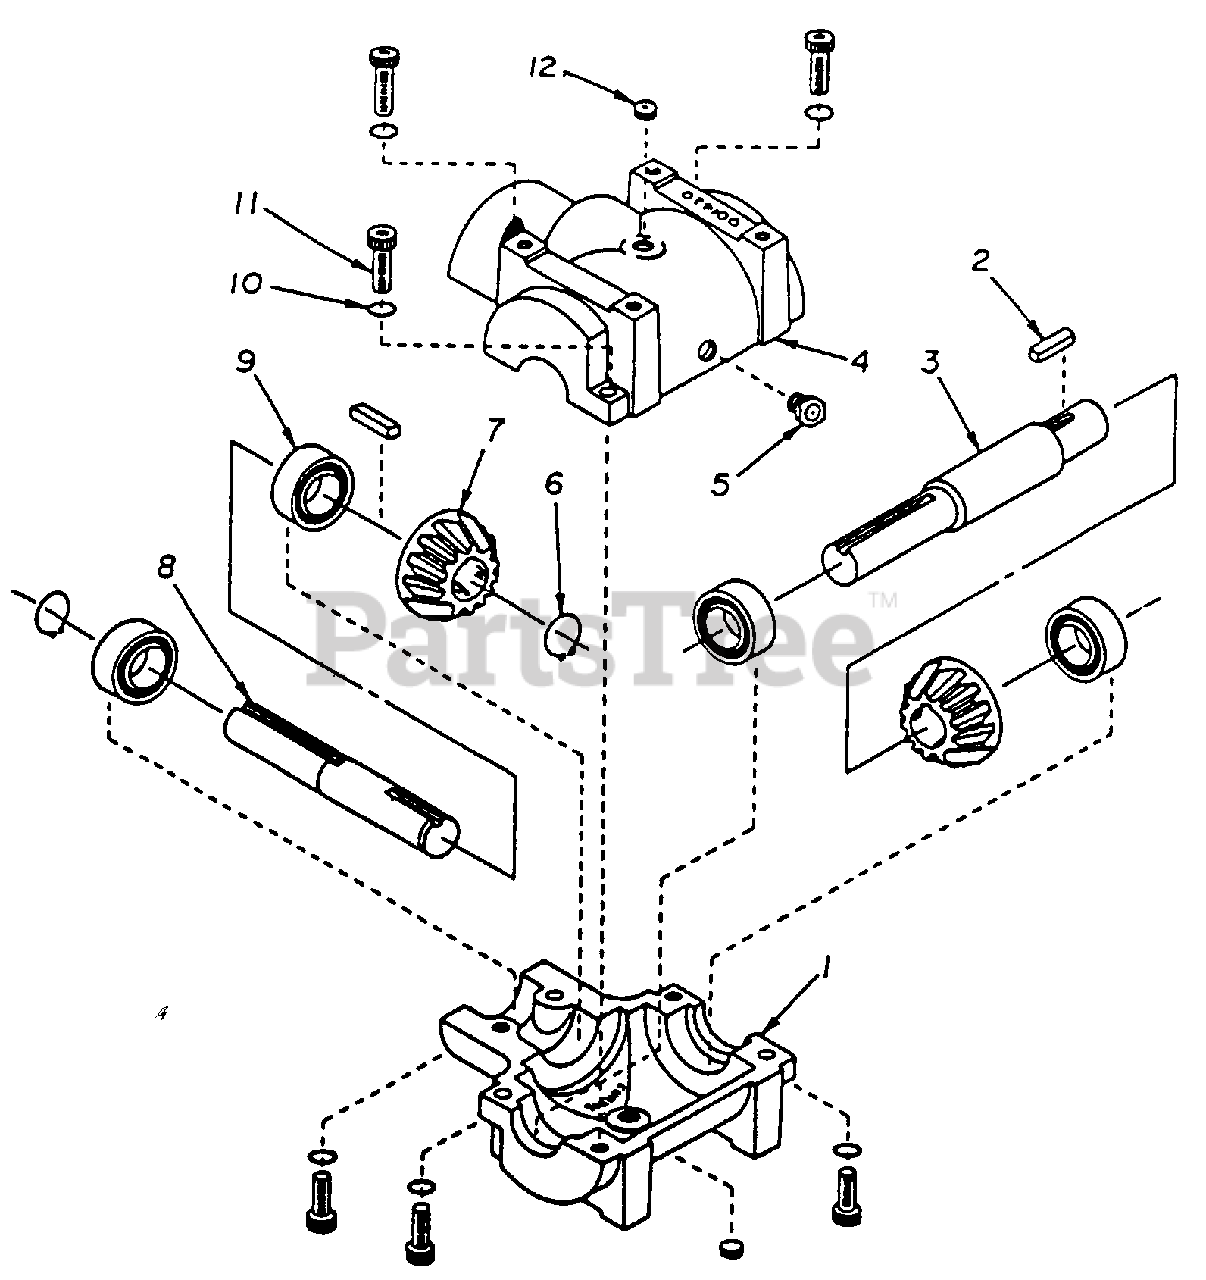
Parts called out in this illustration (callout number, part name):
2	KEY
6	RETAINING RING
9	BALL BEARING
10	LOCKWASHER
11	ALLEN HEAD BOLT
12	PIPE PLUG
